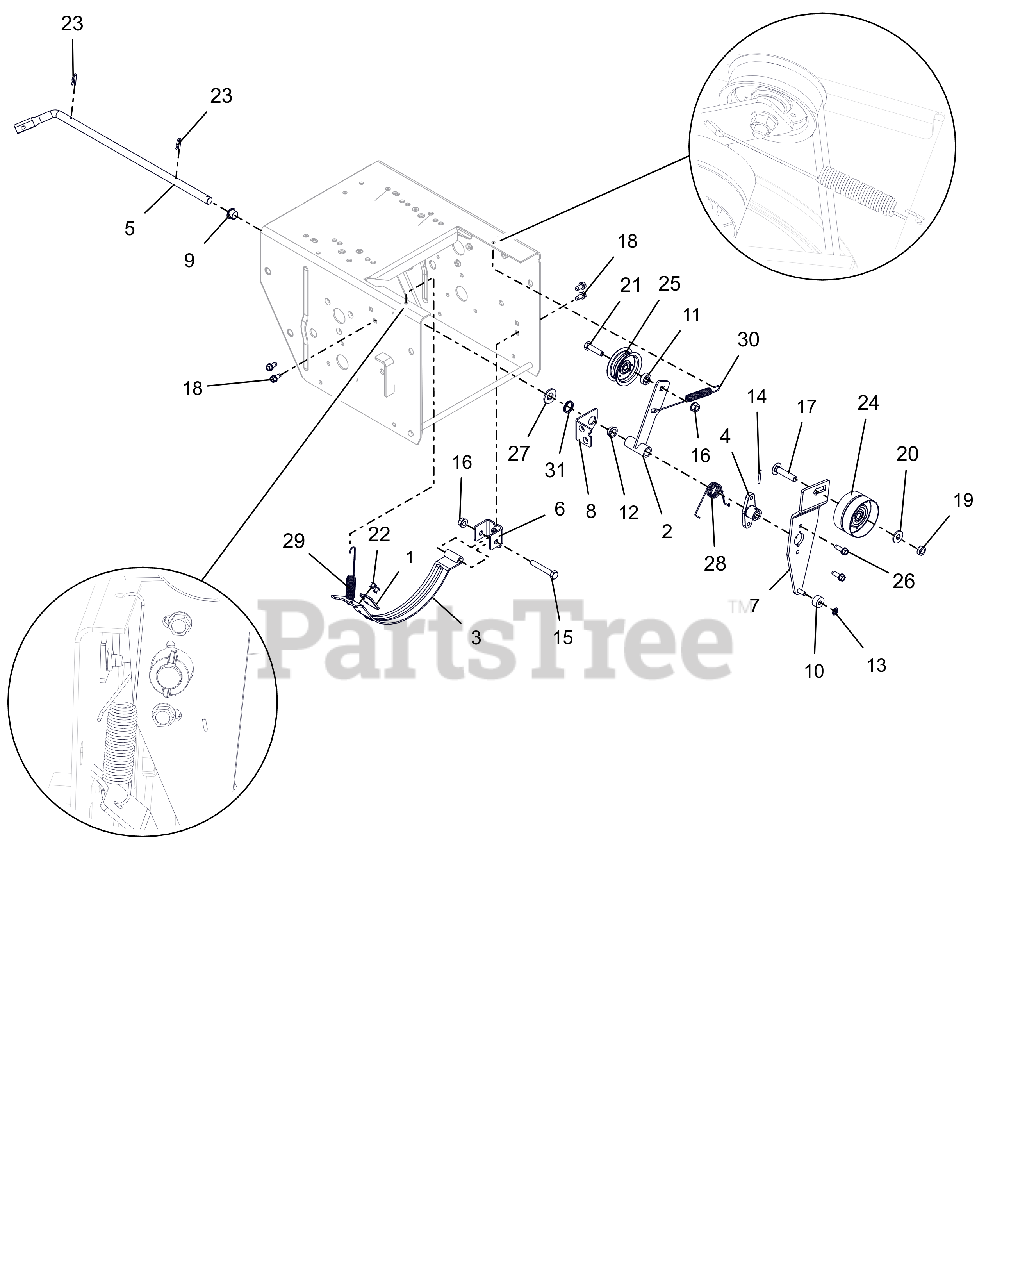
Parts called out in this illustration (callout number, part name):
1	PAD, BRAKE
2	ARM, IDLER-TRACTION
3	ARM, BRAKE-ATTACHMENT
4	HUB, BRAKE ARM
5	ARM, ATTACHMENT
6	PIVOT, BRAKE
7	ARM, IDLER - ATTACHMENT
8	BRACKET, SUPPORT
9	BUSHING, POLYLINER-.50 SPLIT
10	BSHG,SLV .265 X .625 X .375
11	SPCR, BRG .315X.500X.358X.281
12	BSHG,FLANGE .500X.625X.270X.75
13	RG-RTNG-EXT .250X.010
14	PIN-ROLL .125X1.00
15	BLT, HEX .31-18X2.00 G5 ZCC
16	NUT-LK-TOP-FLG .312-18 GF ZCC
17	BLT, RHSSN .38-16X1.75 G5 ZCC
18	SCR-TAP .25-20X.50 HWH ZCC
19	NUT-LK-CTR-JAM .375-16 GB ZCC
20	WSHR,FLT .375X.875X.083 ZCC
21	BLT, HEX .31-18X1.25 G5 ZCC
22	RVT, POP .1875 ZCC
23	CLIP, SPRING
24	IDLER, FLAT-2.75 OD X .375 ID
25	IDLER, FLAT - 2.00"
26	SCR,TAP .25-20X.75 HWH TR ZCC
27	WSHR,FLT .531X1.062X.095 ZCC
28	SG-TORS .067X.88
29	SG-TENS .056X.60X4.40
30	SG-TENS .06X.482X5.35
31	WAVE SPRING .600X.875X.25FH
